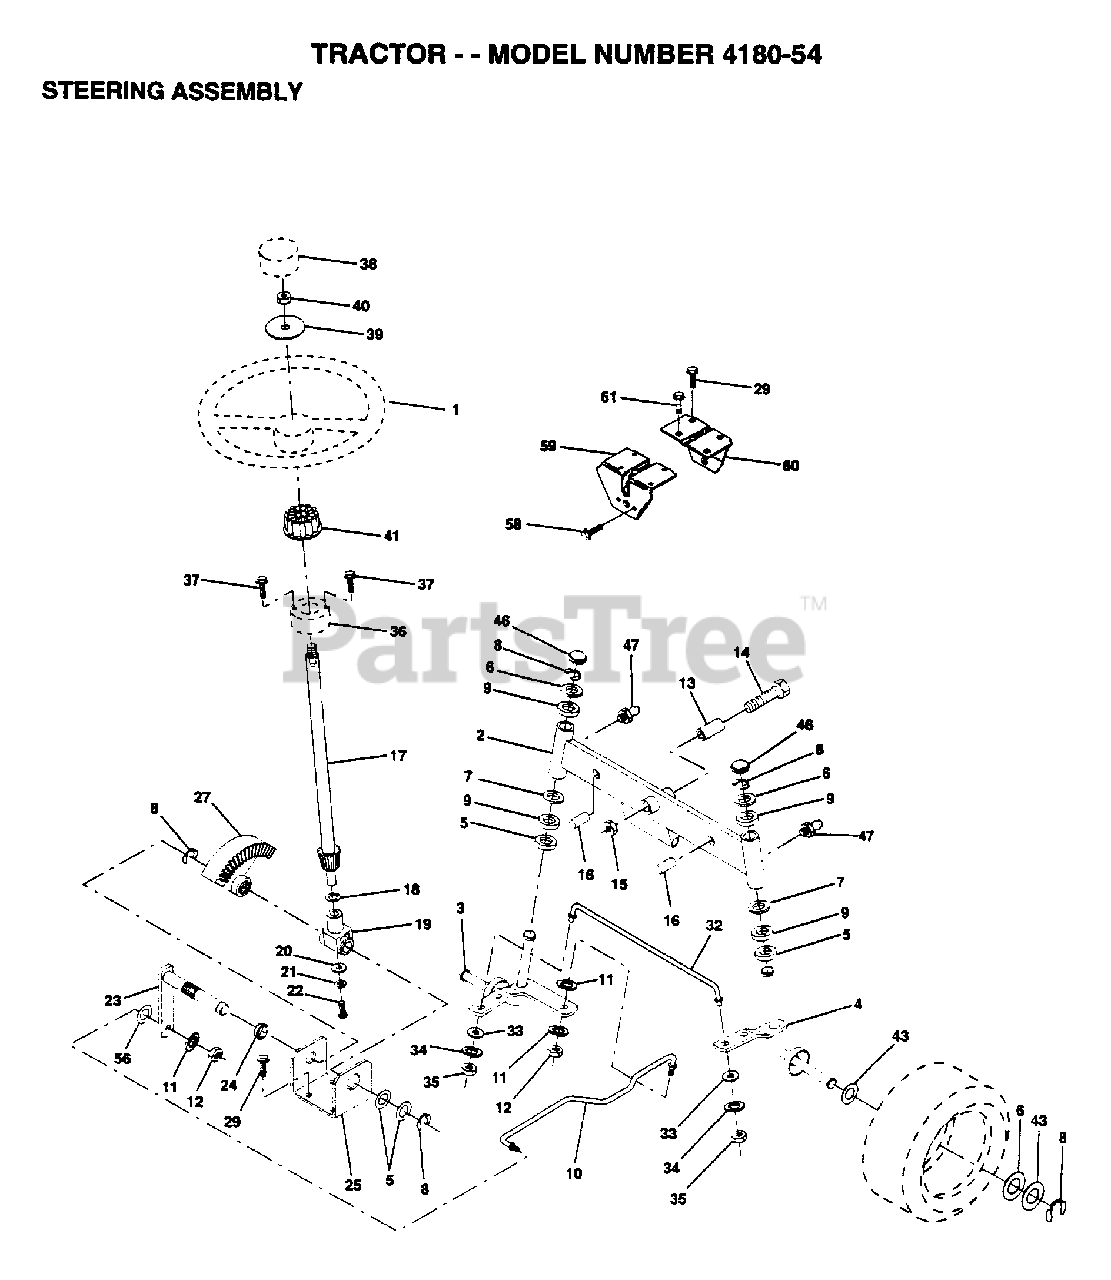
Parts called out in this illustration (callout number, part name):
2	AXLE ASM FRONT
5	WASHER .T
6	WASHER
7	WASHER
8	RING
9	COL. SRTG. BEAR.
11	LOCKWASHER
13	BEARING
14	BOLT LT
15	"NUT-LOC,FLANGE LT"
16	AXLE PIN
18	THRUST WASHER
19	SUPPORT.SHAFT
21	LOCKWASHER
22	"SCREW,SPECIAL"
24	NYLINER T
25	"BRKT,STEERING"
27	GEAR SECTOR
29	SCREW
32	TIE ROD
33	WASHER M
34	LOCKWASHER
35	NUT.LOCK.5/16-24
36	BUSHING.STRG.3/4
37	SCREW.10-24X1/2
38	"INSERT,STR WHEEL"
39	WASHER
41	ADAPTER LT
43	WASHER
46	CAP
47	ZERK M
56	WASHER
58	SCREW LT
59	SUPPORT-SADDL T
60	SUPPORT.SADDLE.FT
61	SCREW SPECIAL
